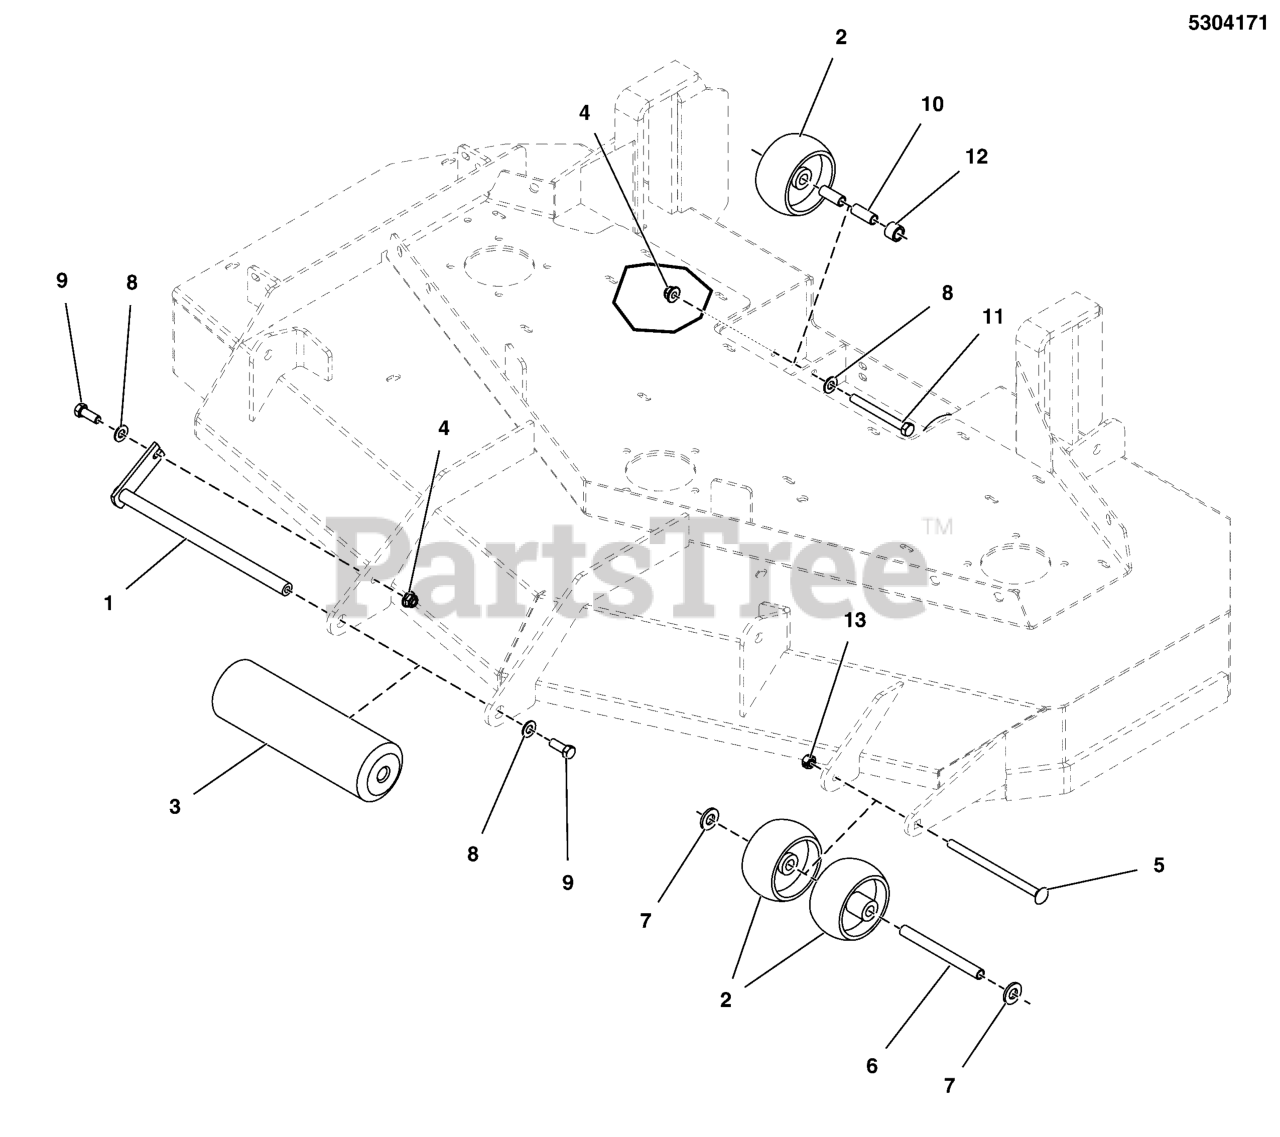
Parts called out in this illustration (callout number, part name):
1	PIN, ROLLER, CZ
2	WHEEL- 2.00 WIDE 3.88 DIA 0.531ID POLY
3	ROLLER, DECK
4	NUT, 3/8-16 HEX NYLOCK FLANGE
5	BOLT, 3/8-16 X 6, CARRIAGE, GD5, CZ
6	SPACER, .38 X .50 X 5.06, CZ
7	WASHER, 1/2 GD9 CZ
8	WASHER, 3/8 SAE
9	BOLT, 3/8-16 X 1" GD5 CZ
10	SPACER, .38 X .50 X 1.25, CZ
11	BOLT, 3/8-16 X 3-1/2" GD5 CZ
12	SPACER, .51 X .75 X .56, PM, CZ
13	NUT, 3/8-16 HEX SIDE LOCK
